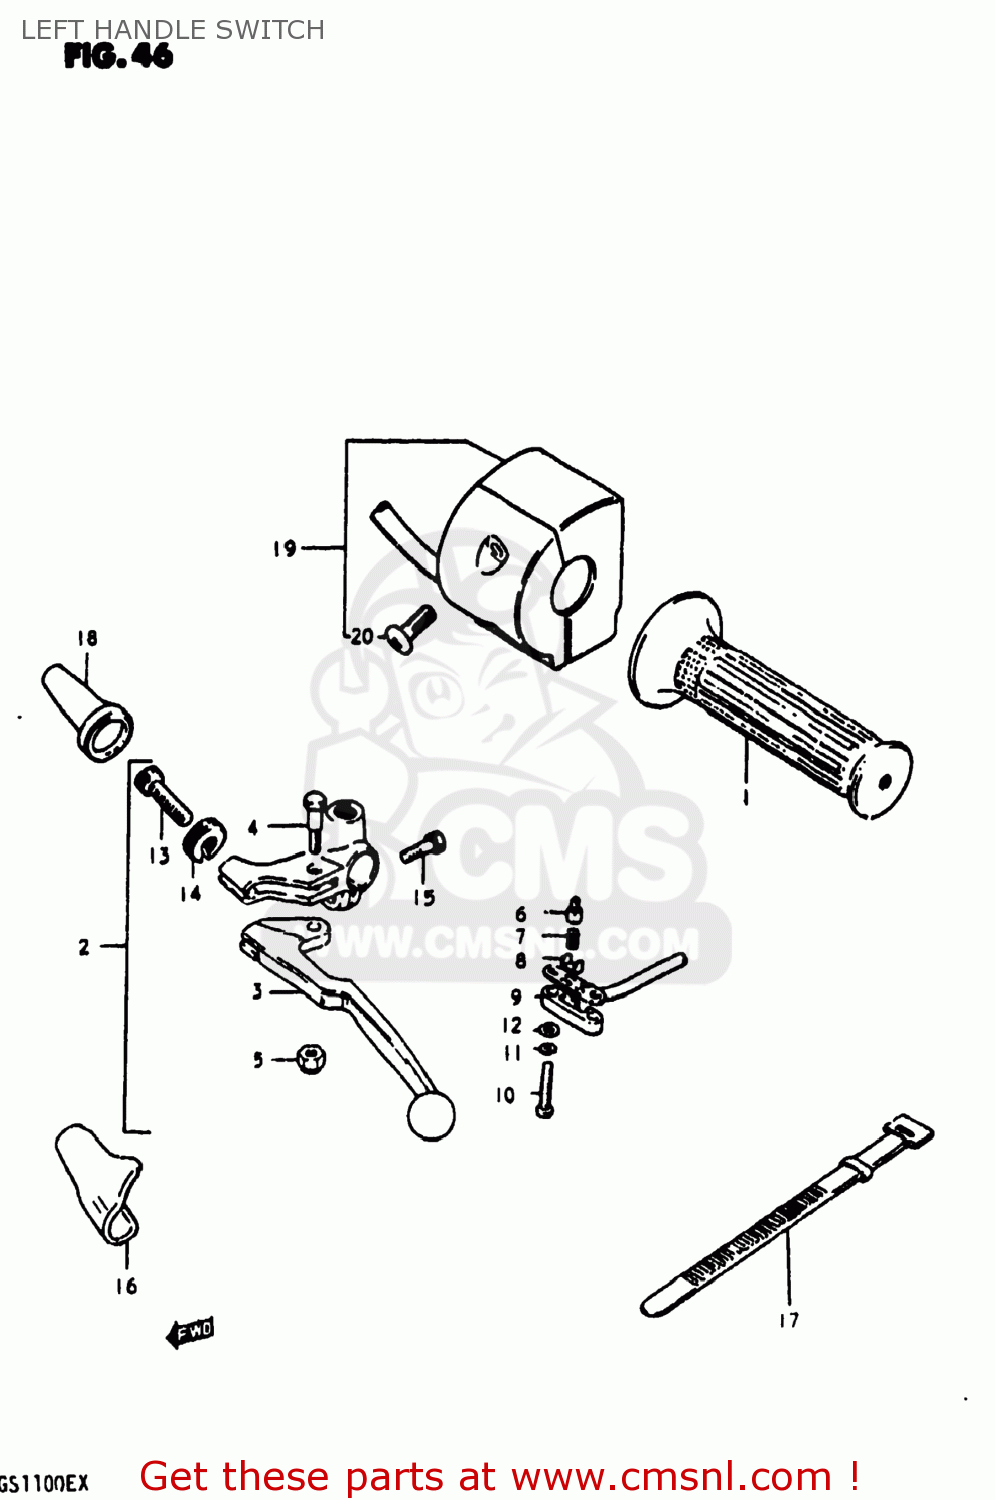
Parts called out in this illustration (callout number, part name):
1	GRIP,LEFT
2	LEVER ASSEMBLY
3	LEVER,CLUTCH
4	BOLT,LEVER
5	NUT
6	HOLDER
7	SPRING
8	PLATE
9	COVER,FR BK TERMINAL BASE
10	SCREW
11	LOCK WASHER
12	WASHER
13	ADJUSTER,CABLE
14	NUT,CABLE ADJUSTER
15	BOLT,CLUTCH LEVER HOLDER
16	COVER,CLUTCH LEVER
17	CLAMP(L:120)
18	BOOT,CLUTCH CABLE
19	SWITCH ASSEMBLY,HANDLE,LEFT
20	SCREW
